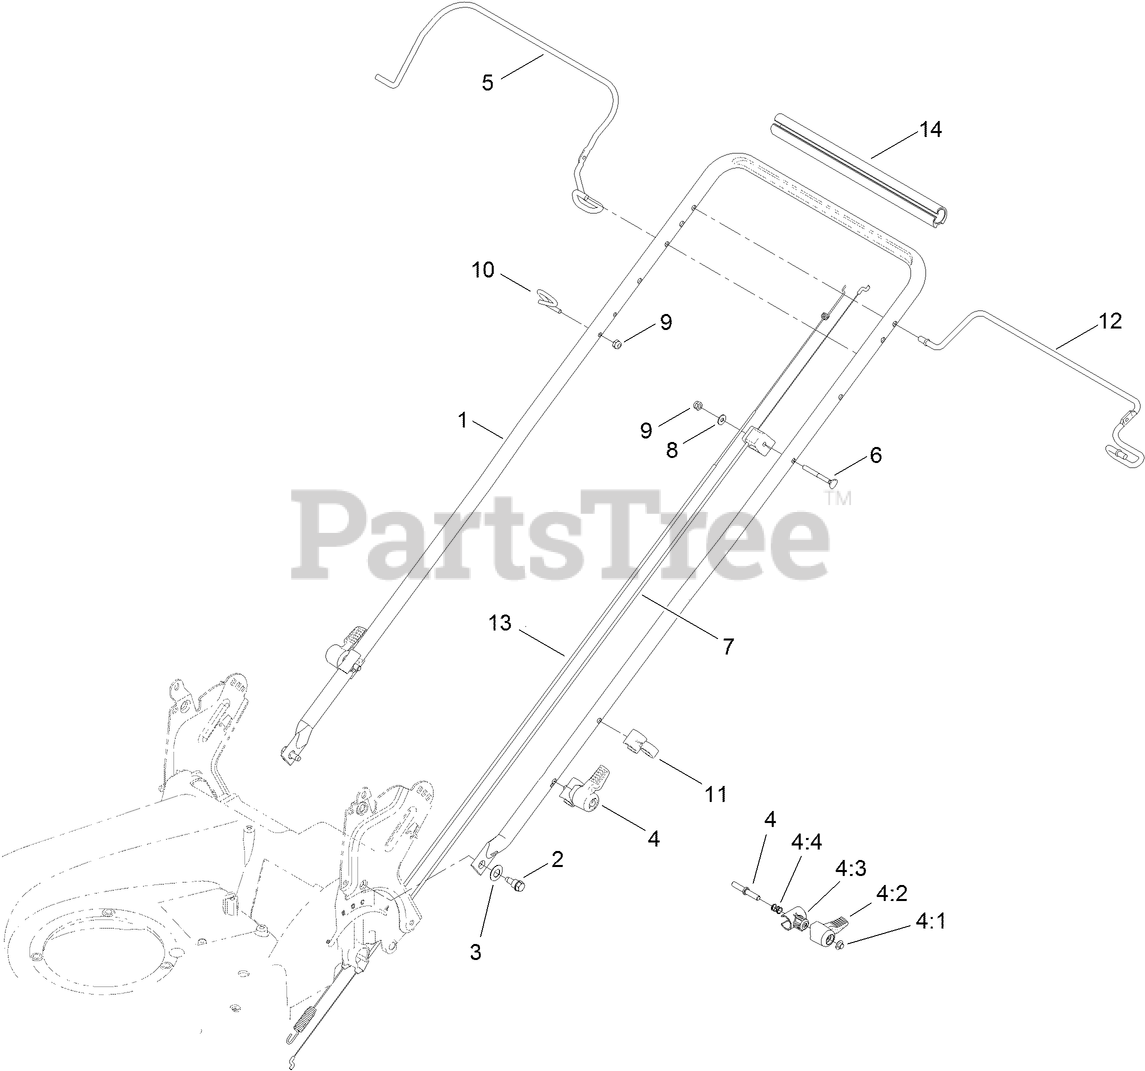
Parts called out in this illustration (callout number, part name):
2	BOLT-SHOULDER
3	WASHER-SPRING, CONICAL
4	QUICK RELEASE ASM
4:2	LEVER
4:3	ANCHOR-SPRING
4:4	SPRING-COMPRESSION
5	BAIL-BRAKE
6	SCREW-HANDLE
7	CABLE-BRAKE
8	WASHER-FLAT
9	NUT-LOCK, NI
10	GUIDE-ROPE
11	GUIDE-CABLE
12	BAIL-TRACTION
13	CABLE-TRACTION
14	GRIP-HANDLE, COMFORT
